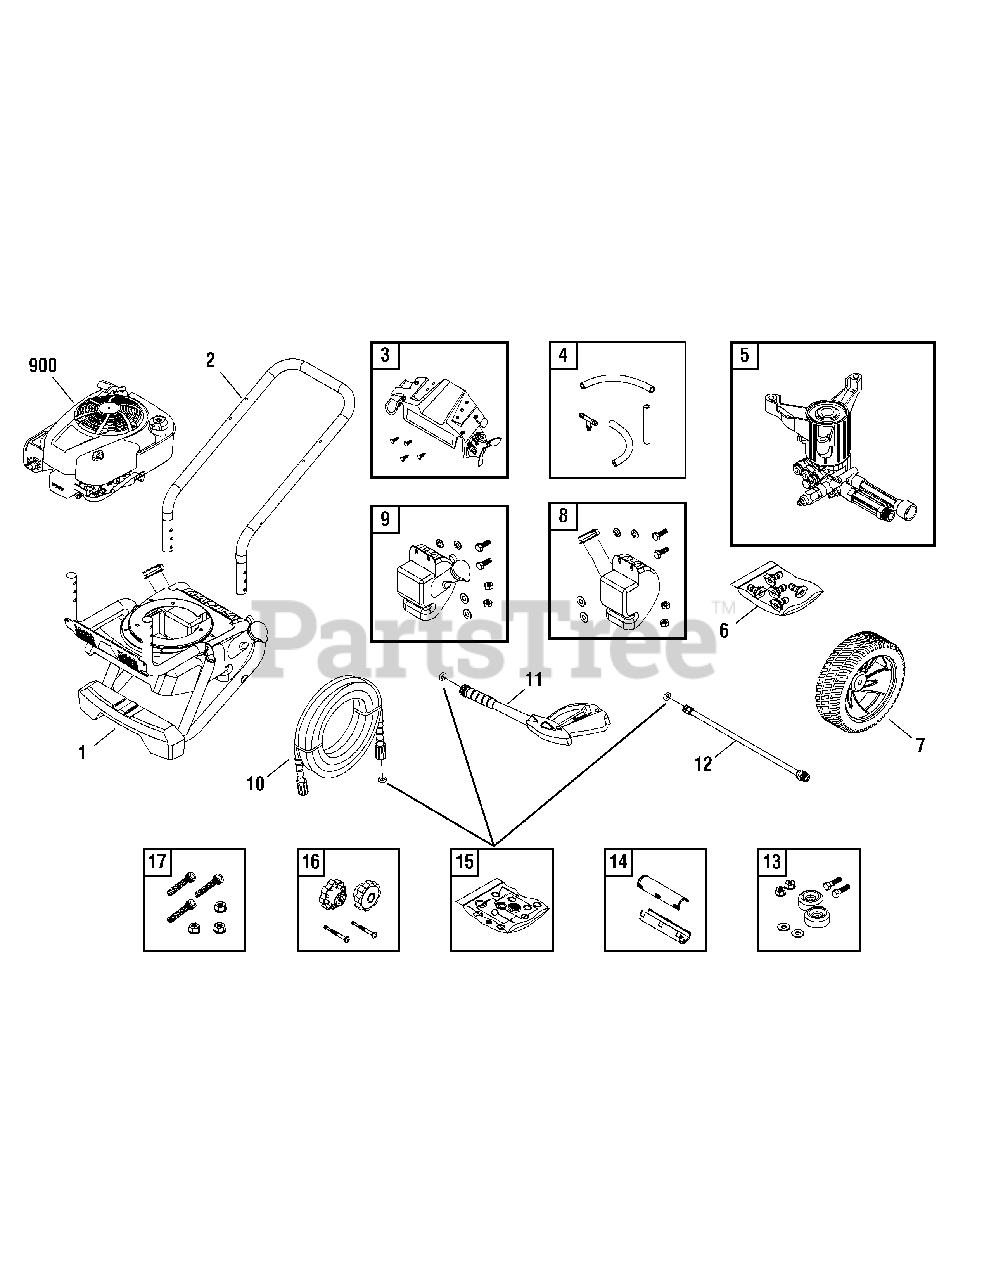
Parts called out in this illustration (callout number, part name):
6	KIT, QC Nozzles
11	GUN
12	EXTENSION, QC
13	MOUNT, Vibration
15	KIT, O-Ring
16	KIT, Hardware, Handle
17	KIT, Hardware, Pump Mounting
900	* ENGINE
